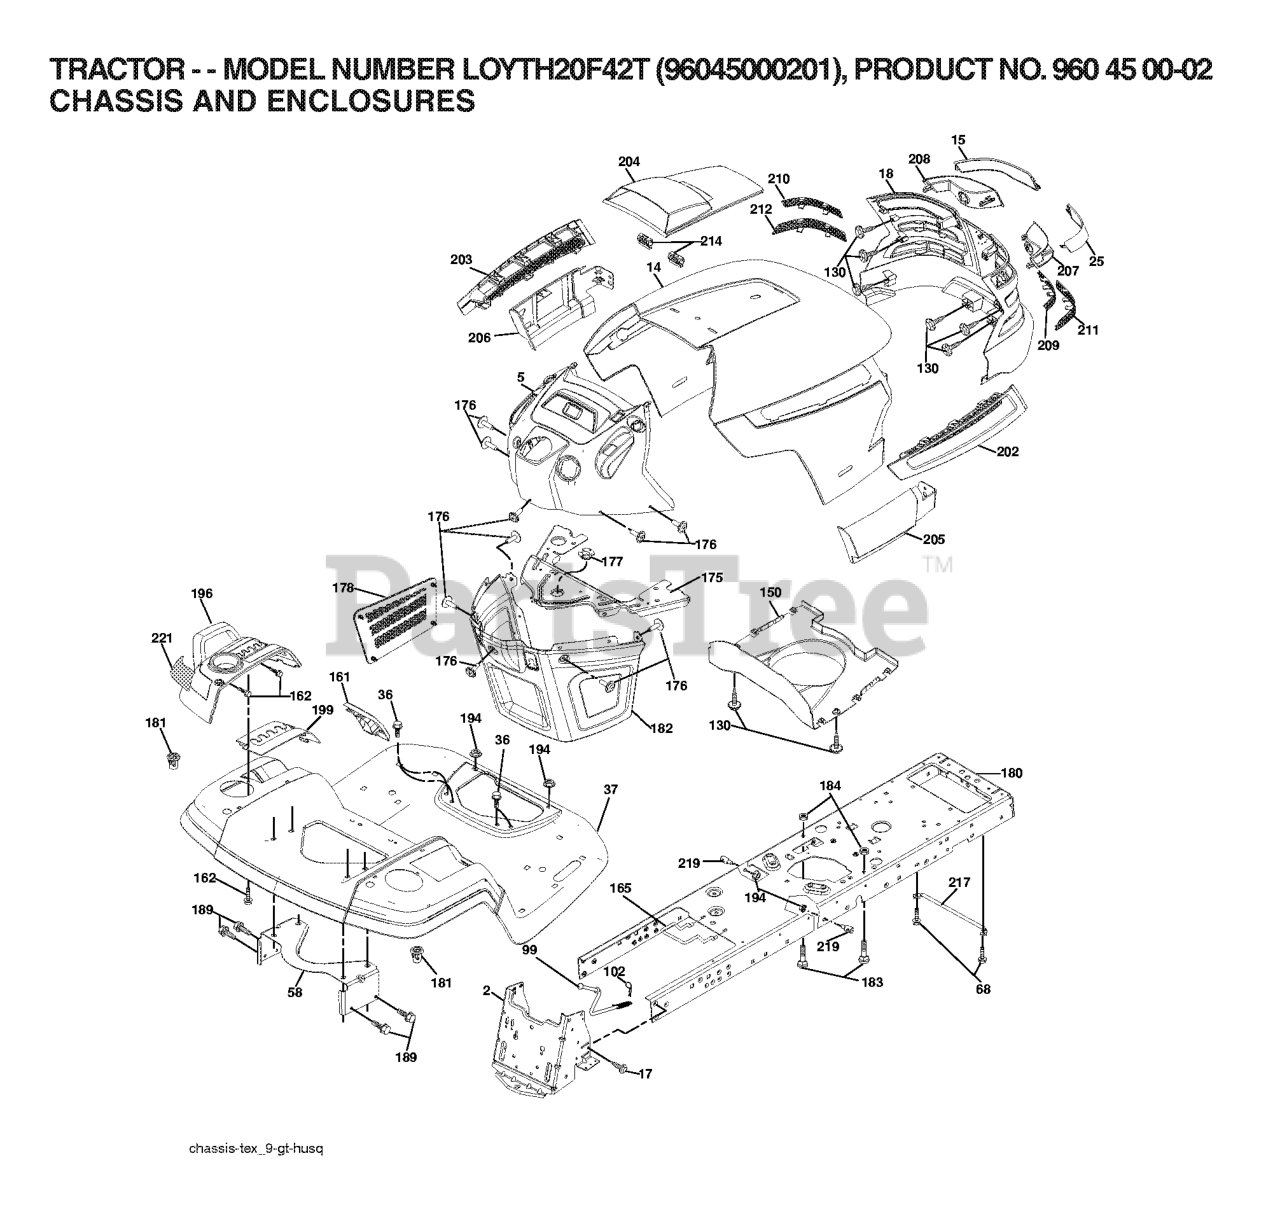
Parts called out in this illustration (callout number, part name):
14	HOOD.PNT.HUSQVARNA.GT.
15	LENS.LH.TEX.GT.HUSQ.CL
17	SCREW 3/8-16X3/4
18	GRILLE.ASM.TX.GT.HUSQ
25	LENS.RH.TEX.GT.HUSQ.CL
36	SCREW 5/16"
37	FENDER.PNT.TX.GT.CH/FW.ORANGE
58	BRKT.SUPPORT.FNDR/TANK
68	Screw 5/16-18 x 1/2 Hex, Self Tapping 5/16-18 x 1/2
102	RETAINER M
130	SCREW
150	AIR.DUCT.TEXGT.HUSQ.SV
161	CONSOLE.FUEL.WINDOW.HU
162	SCREW.HI-LO.CONSOLE
175	PLATE.CROSSMEMBER.HUSQ
176	SCREW.#10-24X5/8.RN.QU
177	BUSHING, STEERING
178	CARGO.ASM.NET.TXGT.W/C
180	CHASSIS.STAMPING.LT/GT
181	BUSHING.MNT.FEND.CRGO.
182	DASH.LOWER.COMMON.12V.
183	BOLT.5/16-18X1-1/4 FULL.THREAD
184	SPACER.FENDER
189	SCREW
194	NUT LOCK HEX FLANGE 5/16-18
196	RP CONSOLE.ASM.DECKLFT.W/
199	PLATE.DECK.LIFT.HUSQVARNA.GT
202	VENT.SIDE.HOOD.HUSQ.RH.GREY
203	VENT.SIDE.HOOD.HUSQ.LH.GRAY
204	VENT.TOP.HOOD.HUSQVARN
205	SKIRT.HOOD.SIDE.HUSQ.RH.GREY
206	SKIRT.HOOD.SIDE.HUSQ.LH.GREY
207	BEZEL.RH.TEX.GT.HUSQ
208	BEZEL.LH.TEX.GT.HUSQ
209	INSERT.HEX.GRILL.HUSQ.GREY
210	INSERT.HEX.GRILL.HUSQ.
211	INSERT.HEX.GRILL.HUSQ.
212	INSERT.HEX.GRILL.HUSQ.
214	CLIP.RETAINER.TINNER.
217	ROD PIVOT CHASSIS/HOOD
219	STUD.FASTNER.W/ANTI-ROTATE
221	REFLECTOR.LH.TEX GT HU
